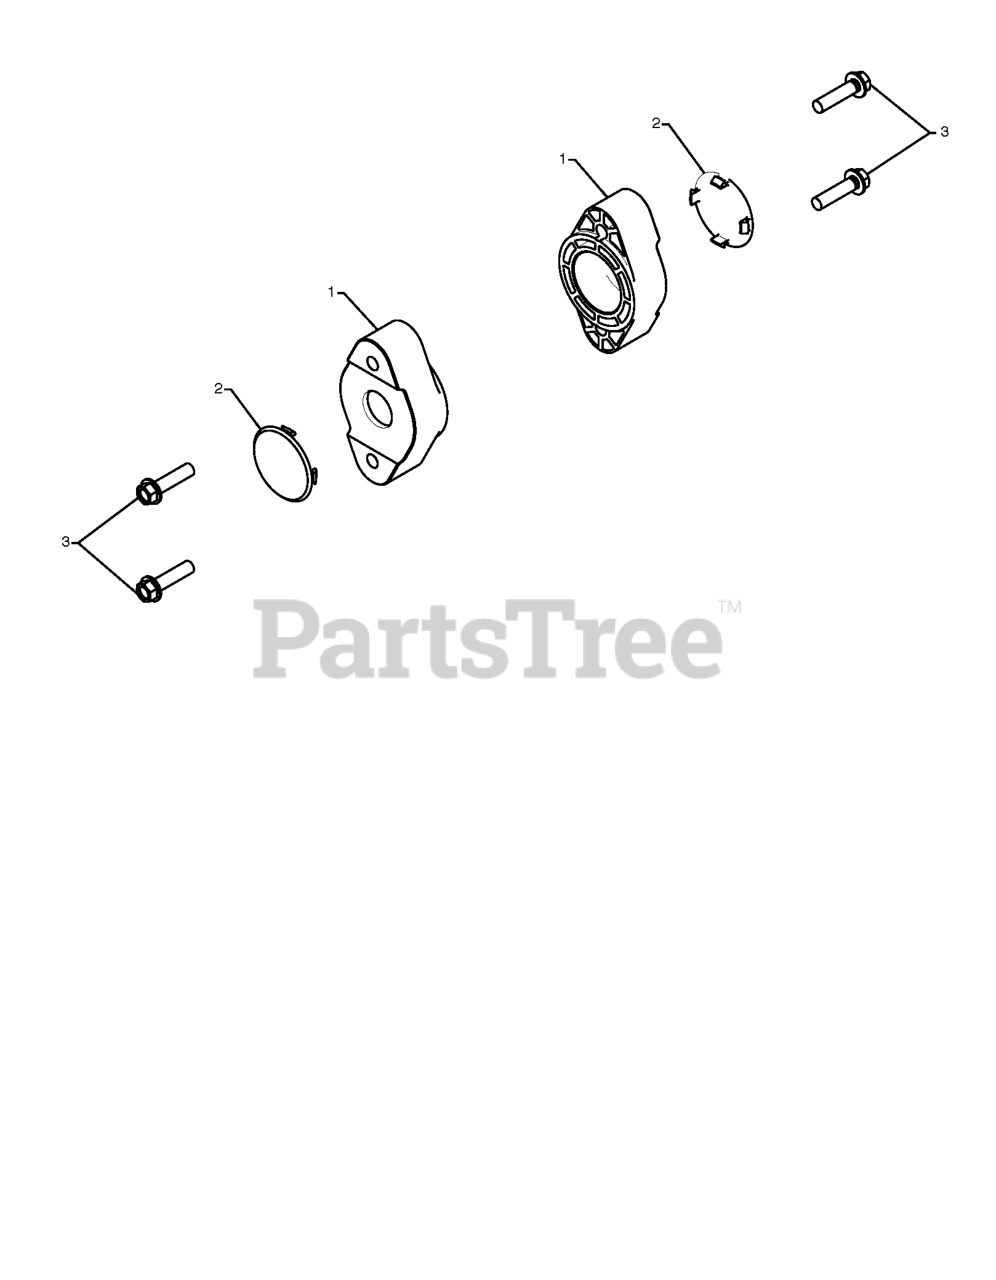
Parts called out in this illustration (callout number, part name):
1	BEARING.AUGER.SHAFT
2	PLUG.BEARING.HOLE.HSG
3	SCREW, HEX HD 5/16X1
